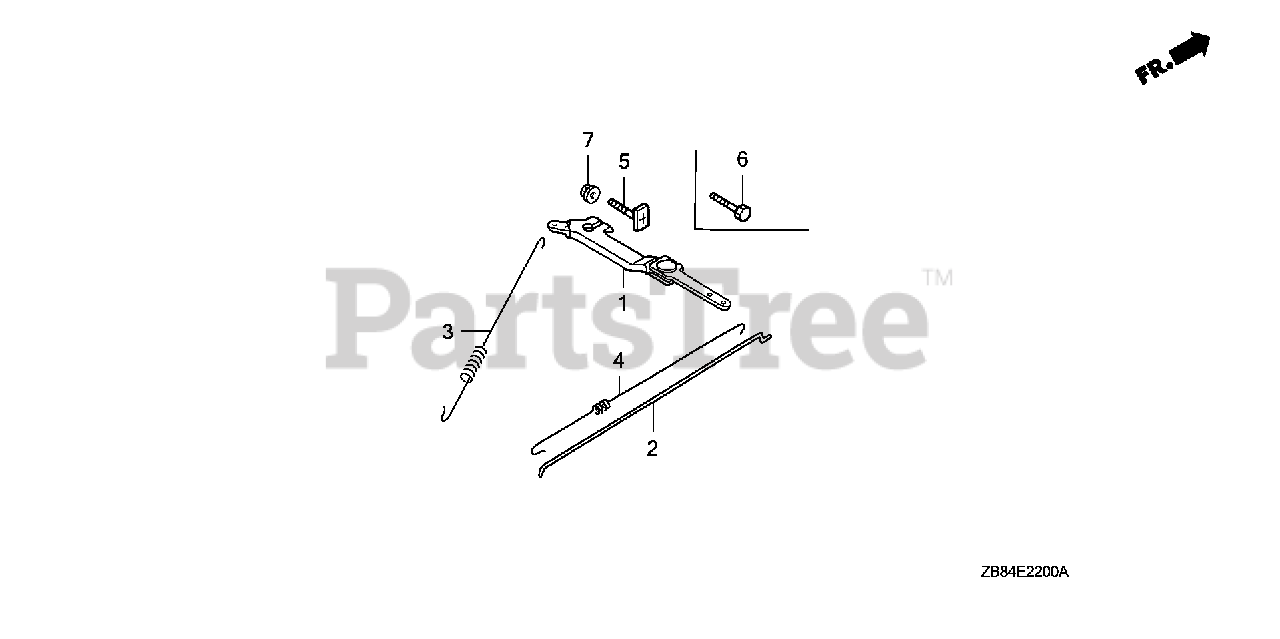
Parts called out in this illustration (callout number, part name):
1	ARM, GOVERNOR
2	ROD, GOVERNOR
3	SPRING, GOVERNOR
4	SPRING, THROTTLE RETURN
5	BOLT, GOVERNOR ARM
7	NUT, FLANGE (6MM)
